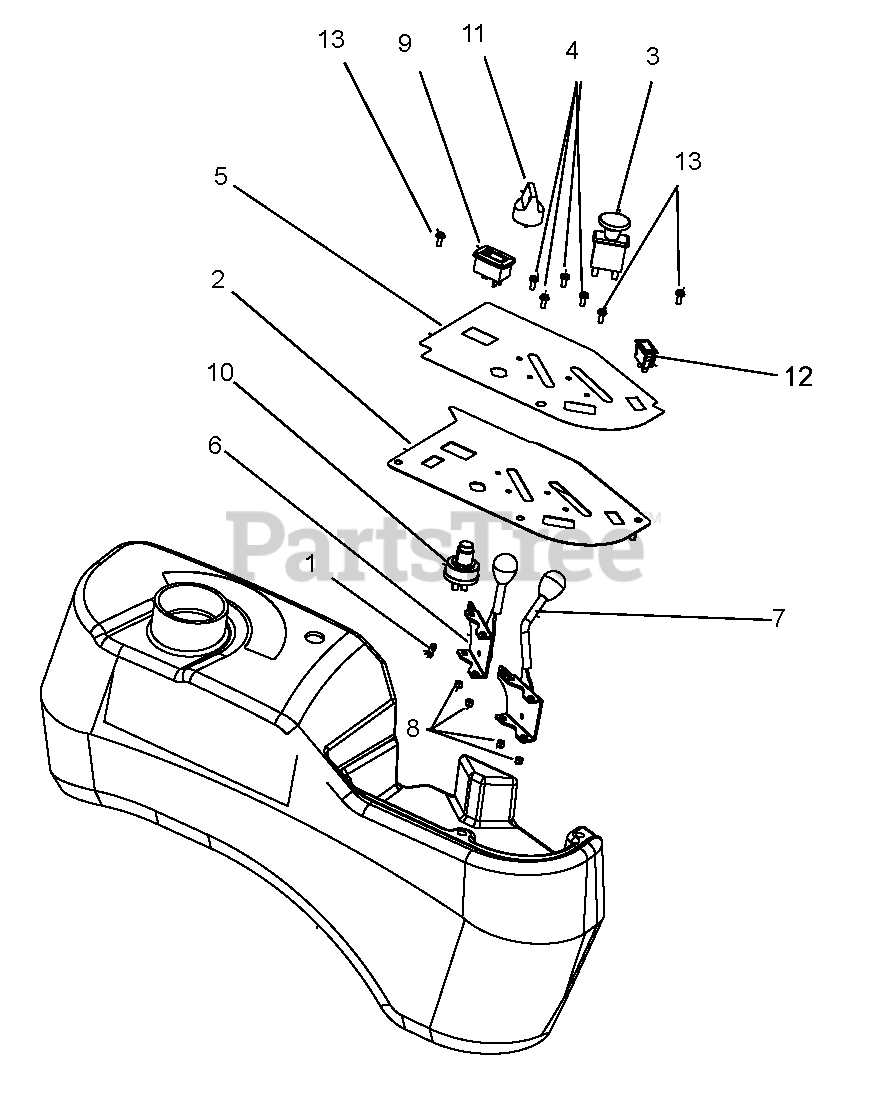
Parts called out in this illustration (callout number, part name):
1	Cable Tie w/ Tree (.25 HOLE)
2	Panel, Control
3	Switch, Clutch
4	Screw-Machine 10-24X.50 Hex Washer Head
5	Decal, Control Panel
6	Cable, Pro-Control Choke
7	Cable, Pro-Contro Throttle
8	Nut, Locking Nylon 10-24 W/INSRT YWZC
9	Meter, Hour w/Maintenance
10	Switch, Ignition
11	Key, w/ Shield
12	Light, Indicator
13	Screw, Machine 10-24 x .50 Hex Washer Head Stainless
